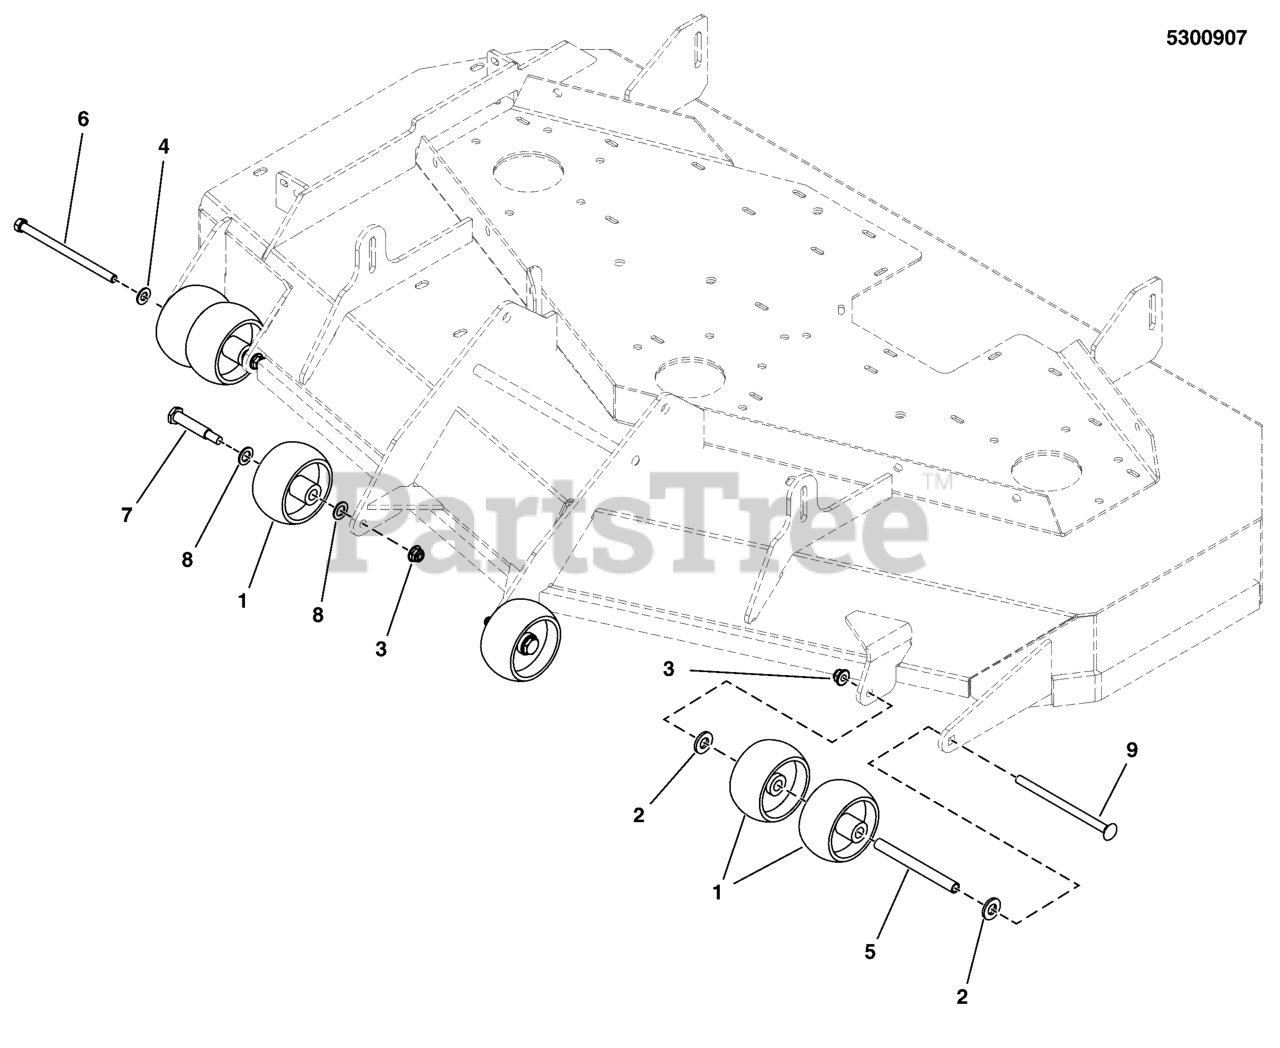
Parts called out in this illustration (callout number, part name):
1	WHEEL- 2.00 WIDE 3.88 DIA 0.531ID POLY
2	WASHER, 1/2 GD9 YZ
3	NUT, 3/8-16 HEX NYLOCK FLANGE
4	WASHER, 3/8 SAE
5	SPACER, .38 X .50 X 5.06
6	BOLT, 3/8-16 X 6" GD5 CZ
7	BOLT-WHEEL 3/8-16X2.781 .750 THRD
8	WASHER,.516IDX.875ODX.06,FLAT,ZC/CL
9	BOLT, 3/8-16 X 6, CARRIAGE, GD5, CZ
